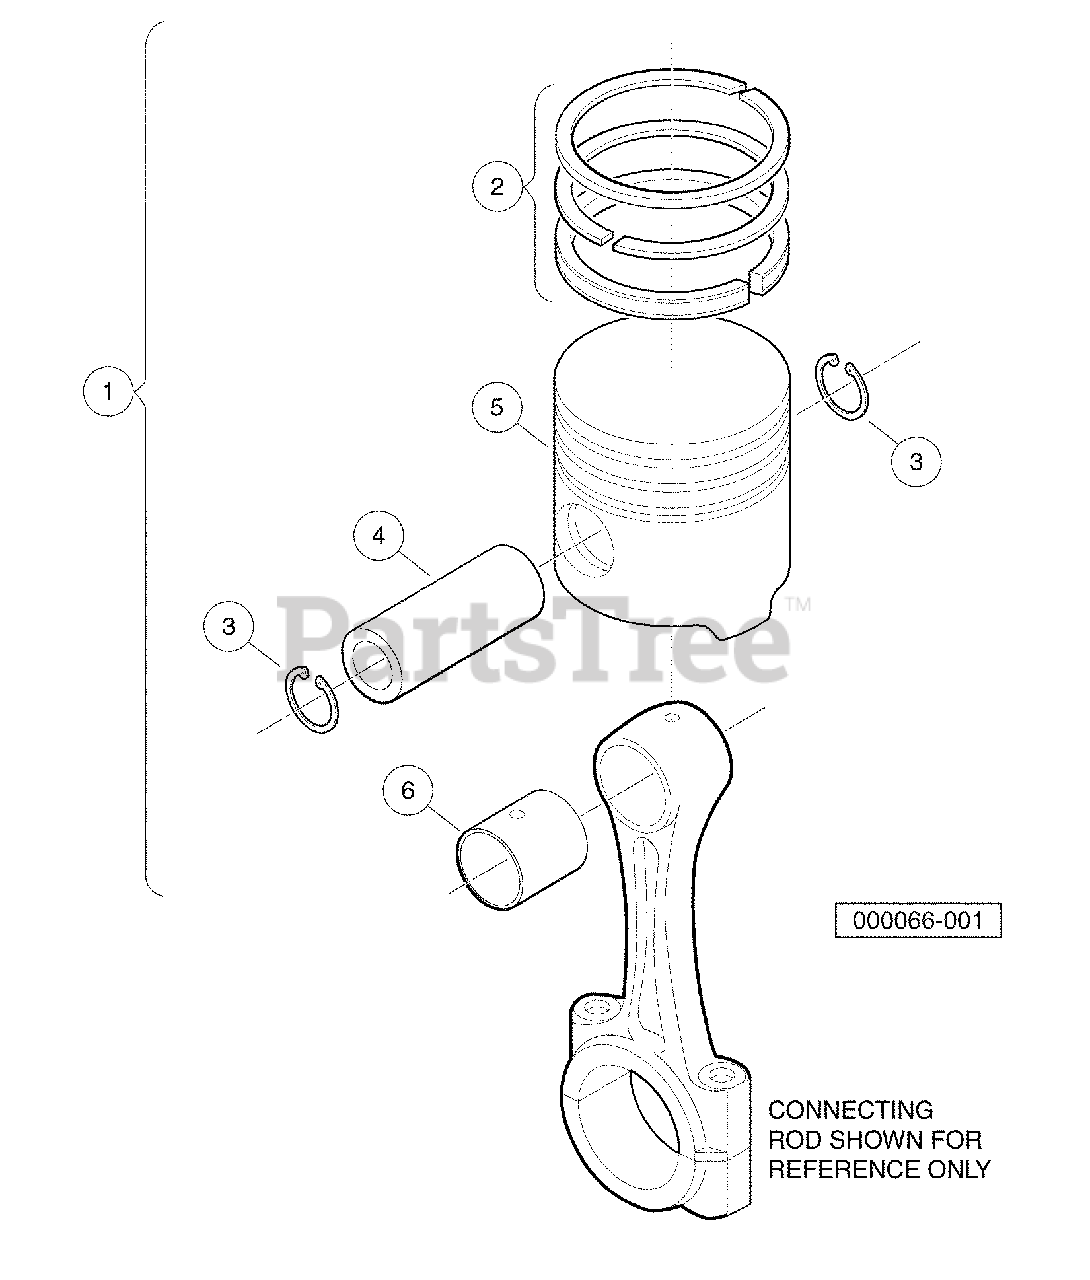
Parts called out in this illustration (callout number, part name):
1	Kit, Piston Rebuild, D722
2	Assy Piston Ring, D722 Std
3	Circlip, Piston Pin
4	Pin, Piston
5	Piston, D722, Std
6	Bushing, Piston Pin, D722
